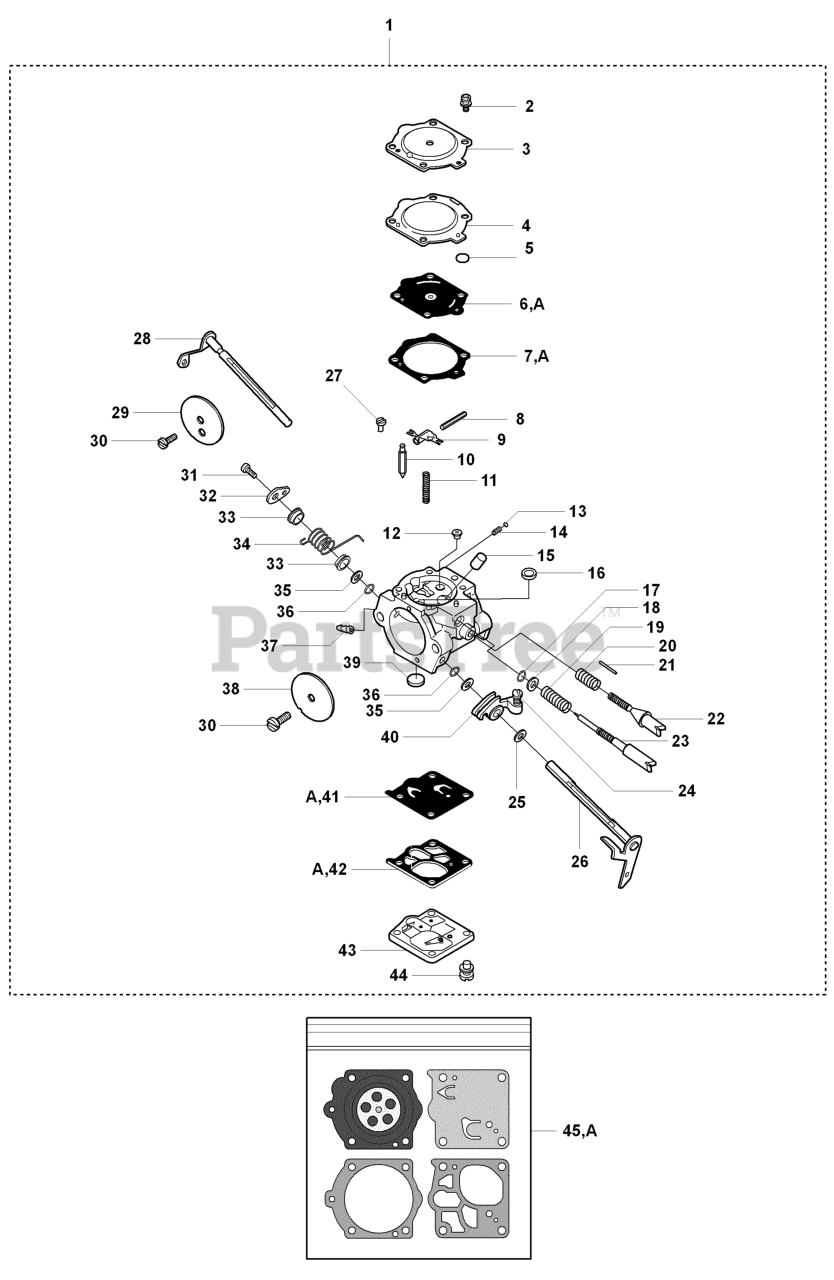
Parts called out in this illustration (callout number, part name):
1	CARBURETOR WGA WALBRO
3	COVER DIAPH
6	METERING DIAPHRAGM GSKT
7	GASKET
10	INLET NEEDLE
11	LEVER SPRING
16	WELCH PLUG
19	PRESSURE SPRING
20	SPRING-MIX NEEDLE
21	ADJ NEEDLE-LO,CARB
22	ADJ SCREW-LO,CARB
23	HI-NEEDLE,CARB
26	THROTTLE SHAFT
29	CHOKE SHUTTER
30	SCREW SHUTTERS
31	SCREW
34	SPRING,THROTTLE RETURN
37	FUEL NIPPLE-CARB
38	SHUTTER-THROTTLE
39	FUEL INLET SCREEN
41	DIAPHRAGM/PUMP
42	GASKET
43	COVER
44	SCREW W/ WASHER
45	DIAPHRAM SET
